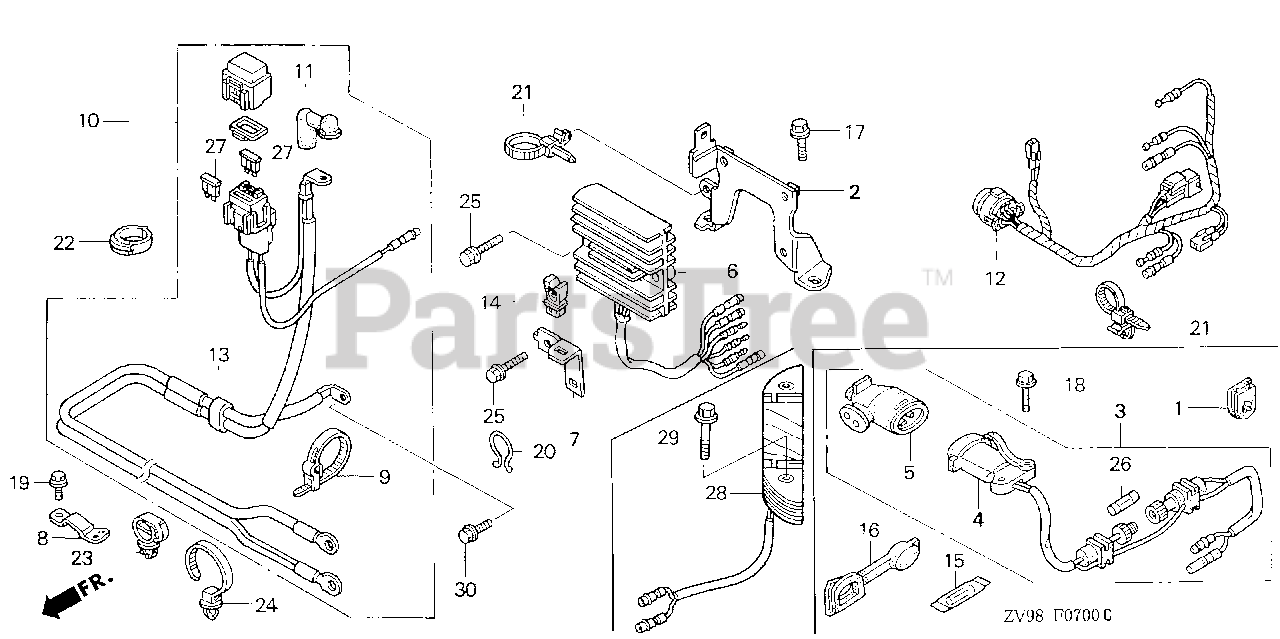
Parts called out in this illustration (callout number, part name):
2	BRACKET, REGULATOR
6	RECTIFIER ASSY., REGULATOR (12V)
7	BRACKET, CONNECTOR
8	BRACKET, CABLE CLIP (S)
9	BAND, WIRE
10	CABLE ASSY., STARTER
11	COVER, TERMINAL
12	CABLE ASSY., REMOTE CONTROL
13	CLAMP, IGNITION WIRE
14	CLIP B, AIR TEMPERATURE SWITCH WIRE
17	BOLT, FLANGE (6X12)
19	BOLT, FLANGE (5X10)
21	STRAP, CABLE (118MM) (BLACK)
22	CLIP, WIRE HARNESS
24	BAND, WIRE HARNESS (123.5MM) (BLUE)
25	BOLT, FLANGE (6X20)
27	FUSE, BLADE (15A)
30	BOLT, FLANGE (6X12) (CT200)
